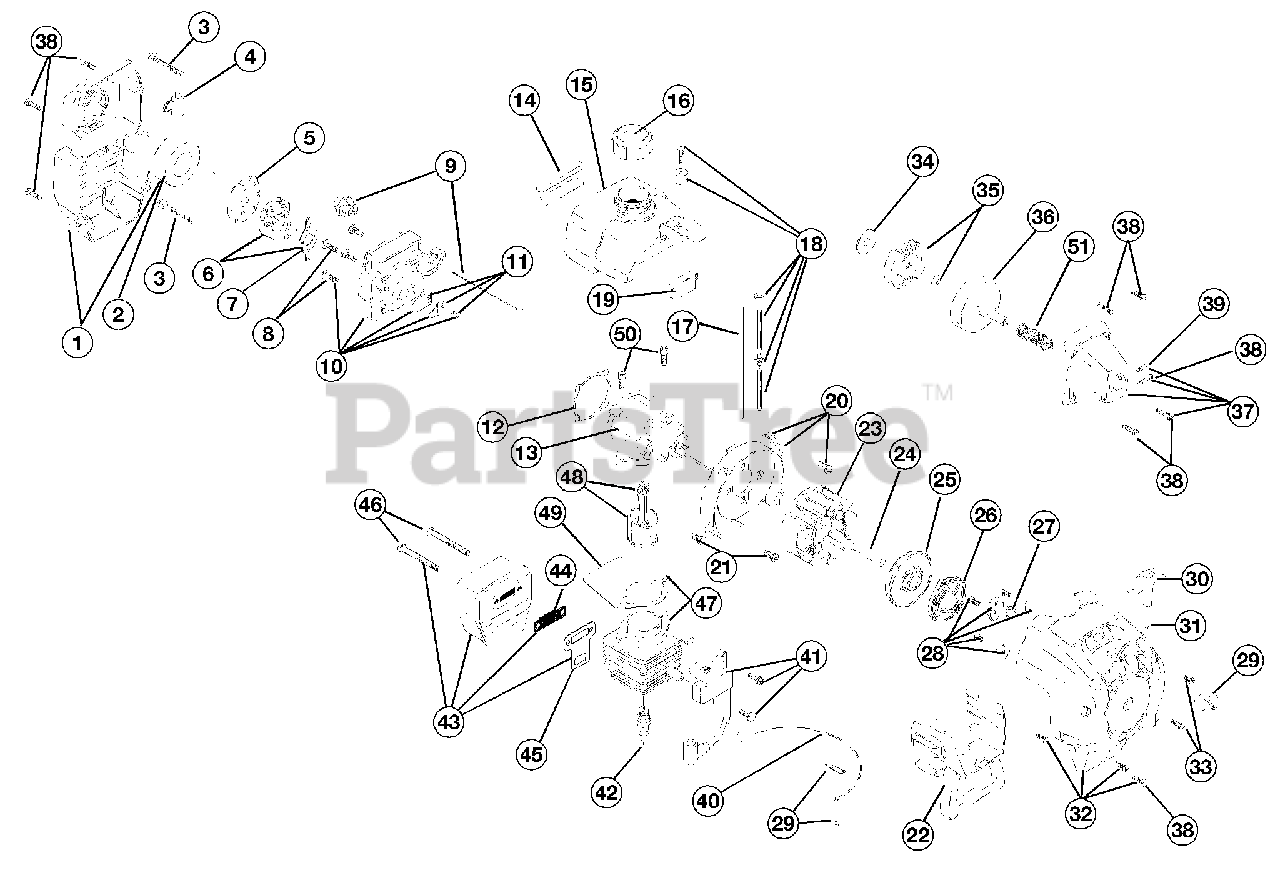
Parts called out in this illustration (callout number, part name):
1	Air Cleaner/Muffler Cover Assembly
2	Air Cleaner Filter
3	Carburetor Mounting Screw Assembly
4	Choke Lever
5	Choke Plate
6	Carburetor Assembly
7	Carburetor Gasket
8	Carb Mount Screw
9	Primer and Hose Assembly
10	Carb Mount Assembly
11	Reed Assembly
12	Carburetor Mount Gasket
13	Crank Case Service Assembly
14	Rear Mounting Pad
15	Fuel Tank Assembly
16	Fuel Cap Assembly
17	Fuel Return Line
18	Fuel Line Assembly
19	Front Mounting Pad
20	Shroud Assembly
21	Shroud Screw
22	Shroud Extension and Stand
23	Flywheel Assembly
25	Recoil Pulley Assembly
26	Recoil Spring
27	Rope Guide
28	Pulley Retainer Assembly
29	Switch Assembly
30	Pull Handle
32	Starter Housing Assembly
33	Housing Screw
34	Clutch Washer
35	Clutch Rotor Assembly
36	Clutch Drum Assembly
37	Clutch Cover Assembly
38	Cover Screw
39	Anti-Rotation Screw
40	Wire Lead
41	Module Assembly
42	Spark Plug
43	Muffler Assembly
44	Spark Arrestor Screen
45	Exhaust Gasket
46	Muffler Mounting Bolt Assembly
47	Cylinder Assembly
48	Piston and Rod Assembly
49	Cylinder Gasket
50	Cylinder Bolt
